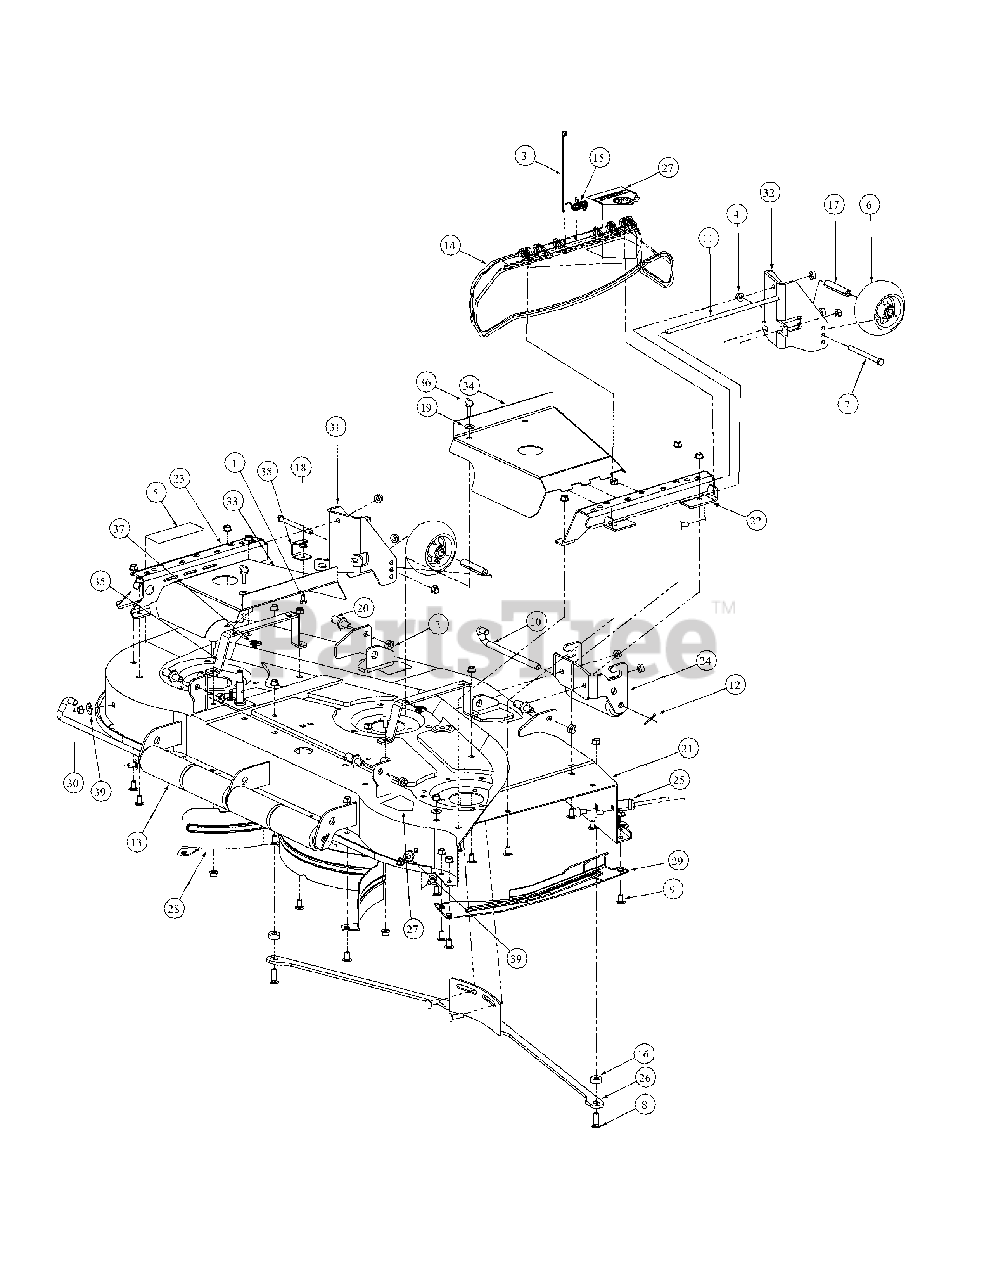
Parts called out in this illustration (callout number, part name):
1	HHCS, 5/16 - 18 x .5"
2	Hex, Jam Nut, 1/2-13
3	Cable Tie, 3/16 x .05 x 7.4
4	Hex Nut, 3/8-16, Flange Lock
5	Decal, Rotating Blade
6	Wheel, 5.00 Diameter
6	Grease Fitting
7	HHCS, 3/8-16, 4.25
8	Carriage Bolt, 3/8-16 x 1.25
9	Carriage Bolt, 3/8 - 16 x .75
10	Roller Pin, 1/2 Diameter x 7.31 Long
11	Hinge Pin, .375 x 12.93
12	Cotter Pin, 1/8 x 1.0
13	Front Roller
14	Deflector Chute
15	Torsion Spring
16	Spacer, .406 ID x 1.00 OD x .38
17	Spacer Wheel
18	Lock Nut, Hex Flange 5/16-18
19	Belle Washer, .325 x .930 x .045
20	Pin, 5/8 Diameter x 1.2 Long
21	Deck Assembly 54", Welded
22	Brace Assembly, Deck, Right Hand
23	Brace Assembly, Deck, Left Hand
24	Roller Bracket, Front 54
25	Stop, Chute, Deflector
26	Guard Assembly, 54 Toe
27	Decal, Danger Hands and Feet
28	Baffle, RR, Inner
29	Guard Assembly, Finger, 54"
30	Roller Pin
31	Mounting Bracket, 54 Left Hand Front Wheel
32	Mounting Bracket, 54 Right Hand Front Wheel
33	Belt Cover, Welded, Left Hand
34	Belt Cover, Welded, Right Hand
35	Support Bracket, 54" Belt Cover
36	Screw Thumb, 5/16-18 x 1.0 Long
37	Nut, U, 5/16-18
38	Stop Bracket
39	Flat Washer, 3/8
